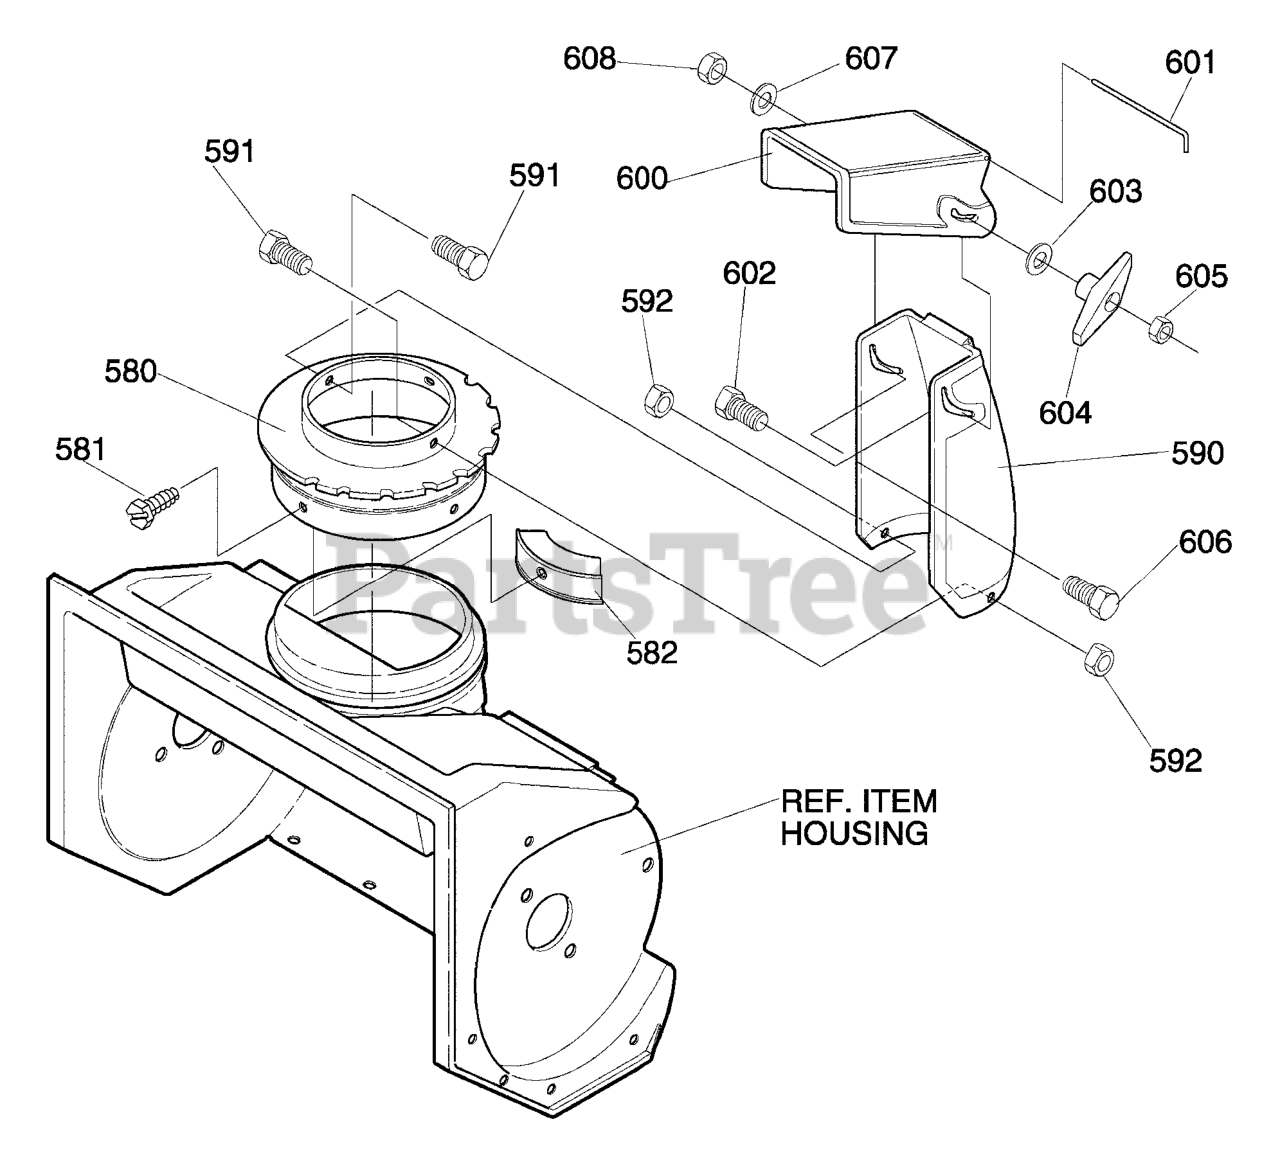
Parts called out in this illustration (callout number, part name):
580	RING, CHUTE
581	SCREW, #10X.50
582	GUIDE, CHUTE
590	CHUTE, LOWER
591	SCREW 1/4-20X.50
592	NUT, 1/4-20
600	CHUTE, UPPER
601	WIRE HINGE
602	BOLT, 5/16-18X1.25
603	WASHER, FLAT
604	KNOB, T
605	NUT, 5/16-18
606	SCREW, 5/16-18 x 0.75
607	WASHER, FLAT
608	NUT, 5/16-18
